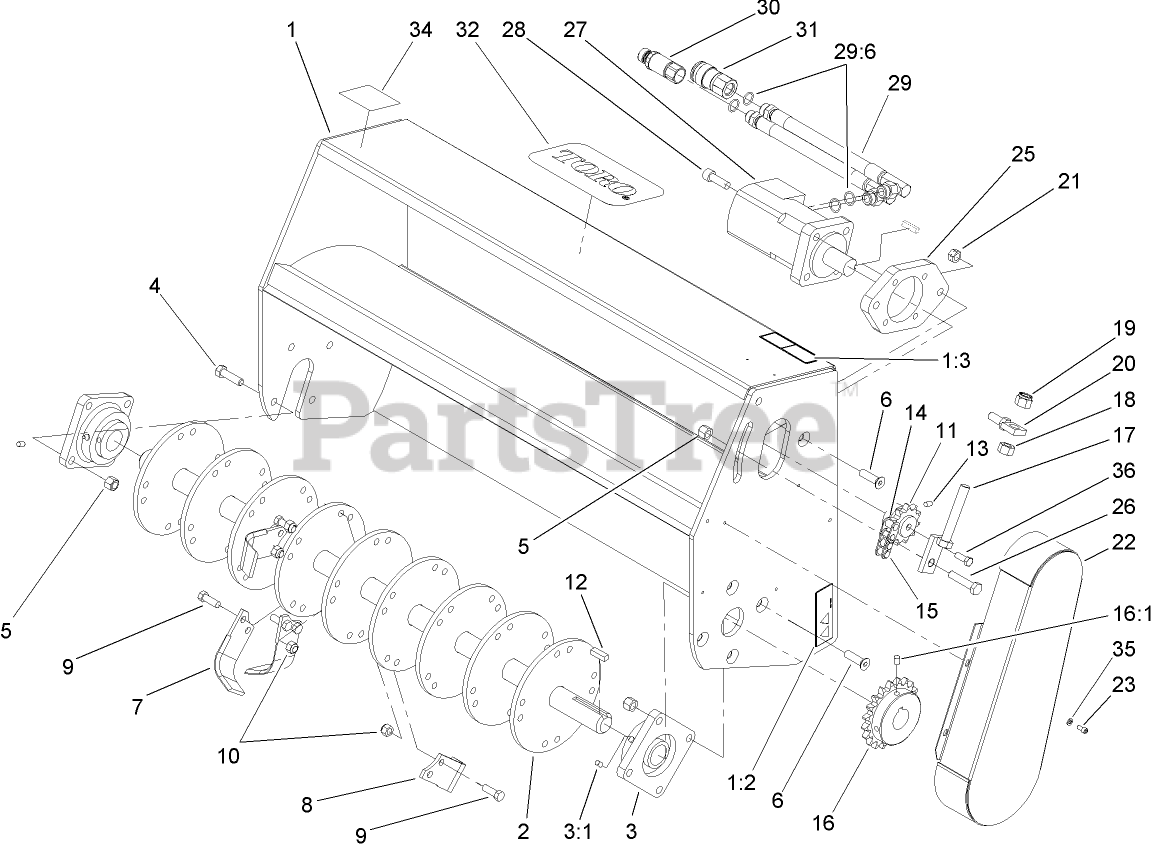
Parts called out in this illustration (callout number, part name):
1	TILLER FRAME ASM
1:2	DECAL-DANGER
1:3	DECAL-WARNING
2	SHAFT-TINE
3	BEARING ASM
3:1	SETSCREW-HSH
4	SCREW-HH
5	NUT-LOCK, NI
7	TINE-RH
8	TINE-LH
9	SCREW-HH
10	NUT-LOCK, INSERT
11	SPROCKET-11 TOOTH
12	KEY-SQUARE
13	SCREW-SET
14	CHAIN-ROLLER
15	LINK-CONNECTING
16	SPROCKET-20 TOOTH
16:1	SCREW-SET
17	CHAIN ADJUSTMENT ASM
18	NUT-HEX
19	NUT-LOCK, NI
20	HOLDER-ADJUSTMENT
21	NUT-SIDE DEFORM
22	COVER-CHAIN, TILLER
23	SCREW-HSH
25	PLATE-MOUNT, MOTOR
26	SCREW-HH
27	MOTOR-HYD
28	SCREW-HSH
29	HYD HOSE ASM
29:6	O-RING
30	NIPPLE-CONNECT, PRESSURE
31	COUPLER-FACE, FLUSH
32	DECAL
34	DECAL
35	WASHER-LOCK
36	SCREW-HH
